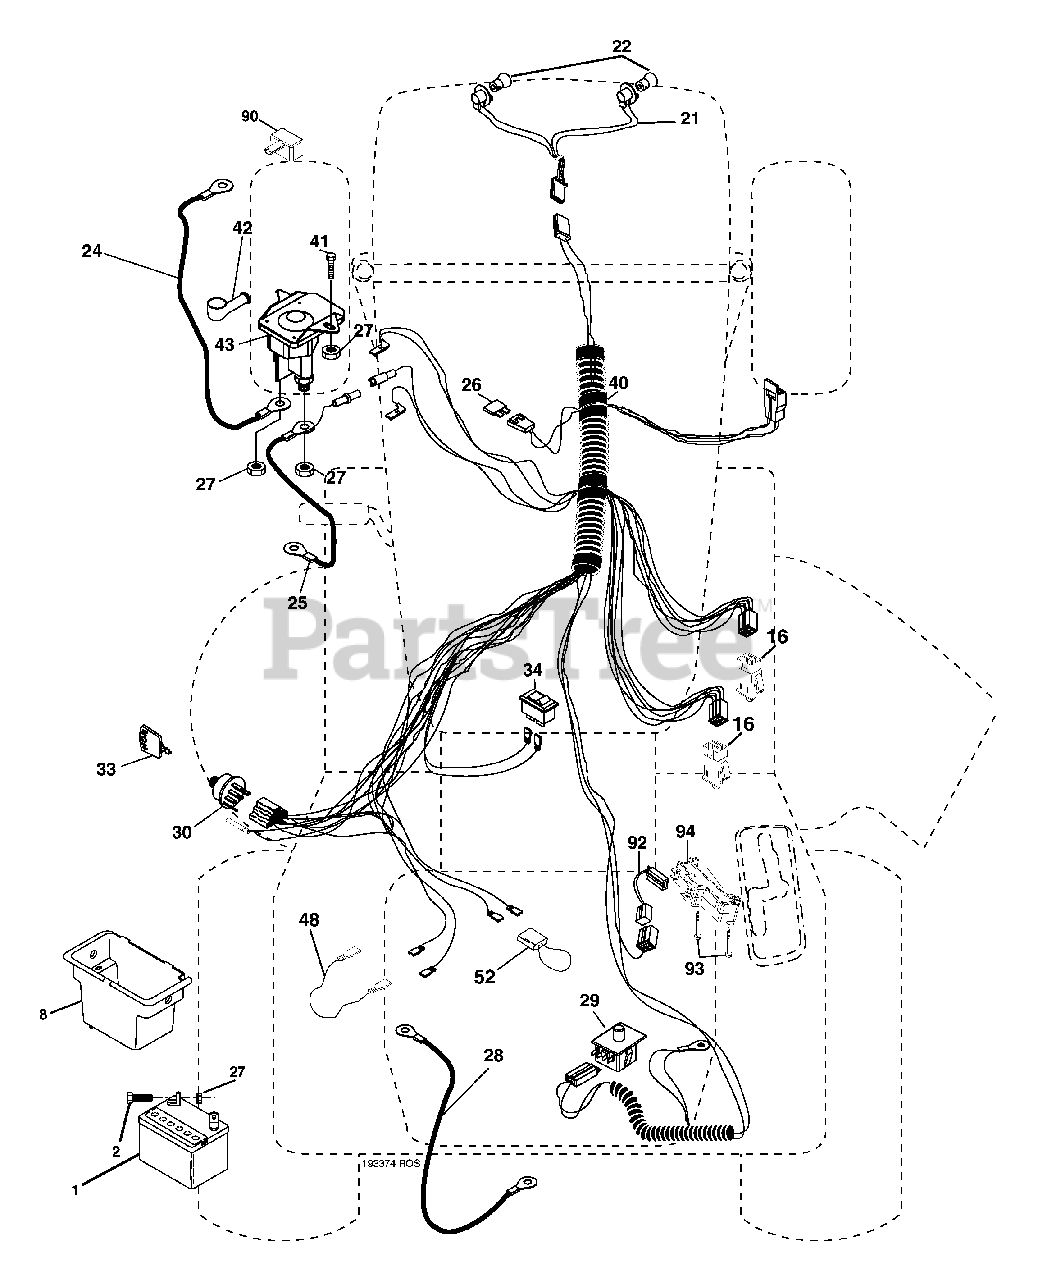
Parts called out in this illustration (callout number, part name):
1	Battery
2	Bolt Hex Hd 1/4-20 unc x 3/4
8	Box Battery
16	Switch Interlock
21	Harness Socket Light
22	Bulb, Light # 1156
24	Cable Battery
25	Cable Battery 6 Ga.Red w/16 wire 44"
26	Fuse
27	Nut Keps Hex 1/4-20 unc
28	Cable Ground 12" Blk 6 Ga.
29	Switch Seat
30	Switch Ign
33	Key Ign Molded Generic
34	Switch Light/Reset
40	Harness Ign
41	Bolt Fin Hex 1/4-20 unc x 1/2
42	Cover Terminal Red
43	Solenoid
48	Adapter Ammeter
52	Protection Loop
90	Cover Terminal
92	Harness Pigtail Reverse Switch
93	Screw Plastic 10-14 x 2.0
94	Modual Reverse ROS
